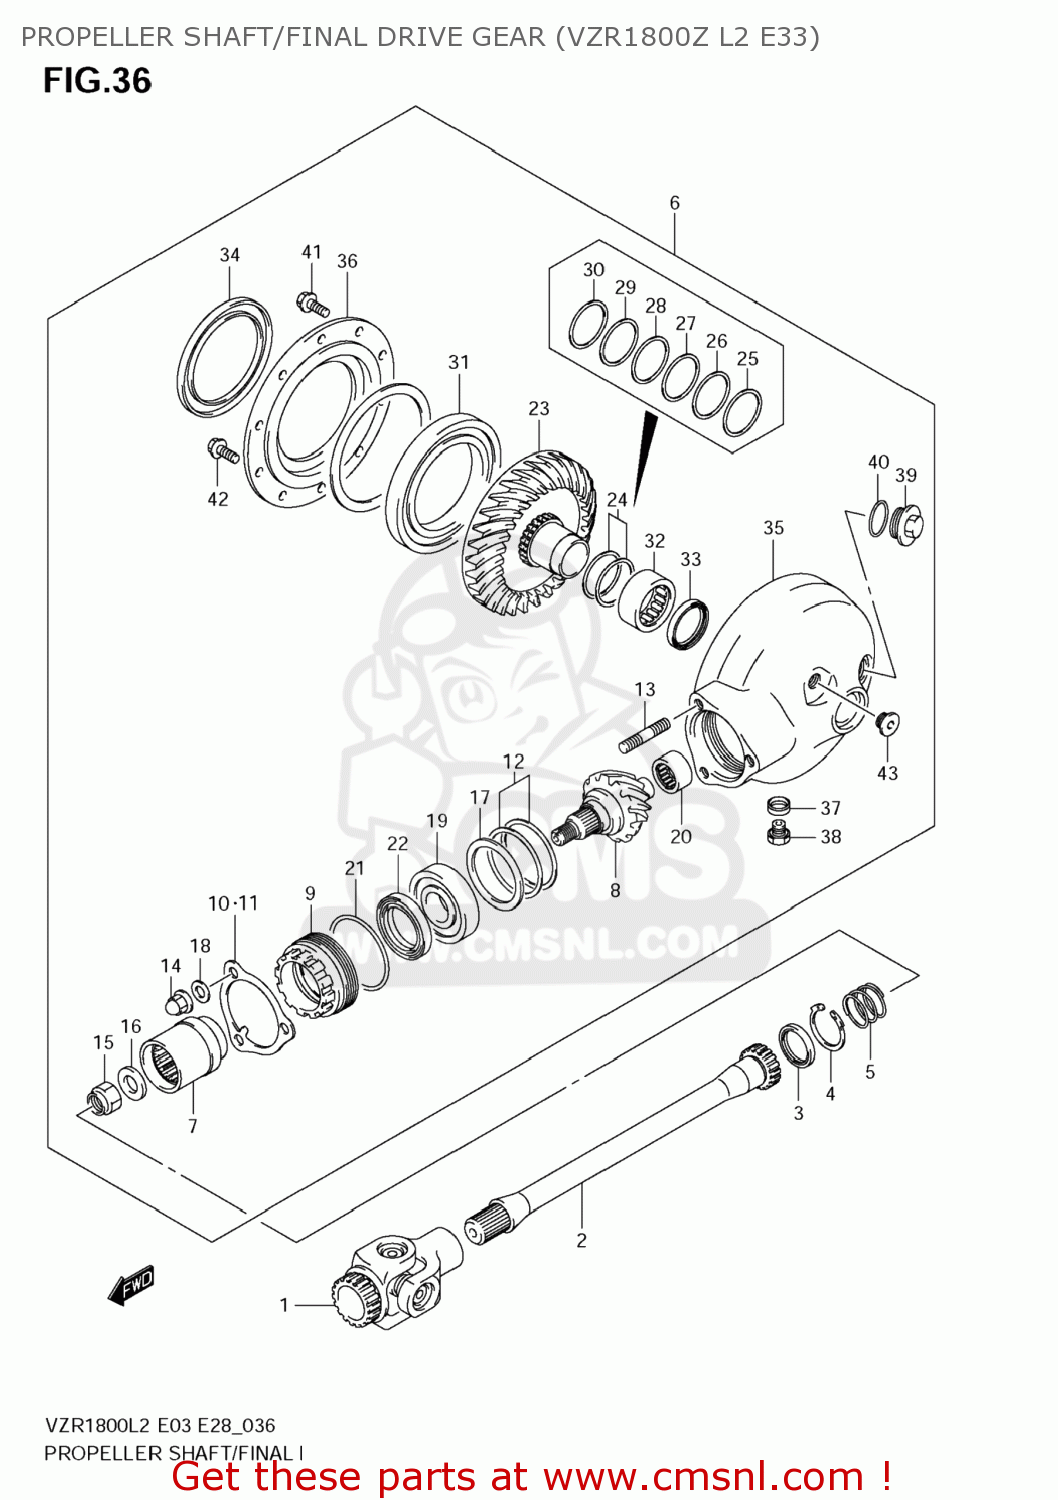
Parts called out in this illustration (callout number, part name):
1	YOKE,UNIVERSAL JOINT
2	SHAFT,PROPELLER
3	SEAL,OIL(30X40.5X5.5)
4	CIRCLIP
5	SPRING
6	GEAR & CASE SET,FINAL BEVEL
7	COUPLING,FINAL DRIVE GEAR
8	GEAR,FINAL DRIVE BEVEL
9	STOPPER,FINAL DRIVE BEARING
10	PLATE,BEARING STOPPER
11	PLATE,BEARING STOPPER
12	SHIM SET,FINAL DRIVE GEAR
13	BOLT,STUD
14	NUT
15	NUT
16	WASHER(16X29X4)
17	WASHER(54X68X1.5)
18	WASHER
19	BEARING(28X68X18)
20	BEARING(20X34X18)
21	O RING(D:3.1,ID:63.9)
22	SEAL,OIL
23	GEAR,FINAL DRIVEN BEVEL
24	SHIM SET,FINAL DRIVEN GEAR,R
25	SHIM(40X46.8X0.95)
26	SHIM(40X46.8X1.05)
27	SHIM(40X46.8X1.1)
28	SHIM(40X50X1.2)
29	SHIM(40X50X1.4)
30	SHIM(40X50X1.5)
31	BEARING(85X130X14)
32	BEARING(40X50X20)
33	SEAL,OIL(38X46X6)
34	SEAL,OIL(85X110X11)
35	CASE,FINAL GEAR
36	CASE,FINAL GEAR BEARING
37	GASKET(13.8X18.8X4.8) (NAS)
38	PLUG(MAGNETO)
39	PLUG,30X9
40	O RING(D:3.1,ID:26.4)
41	BOLT
42	BOLT
43	PLUG,16X8
